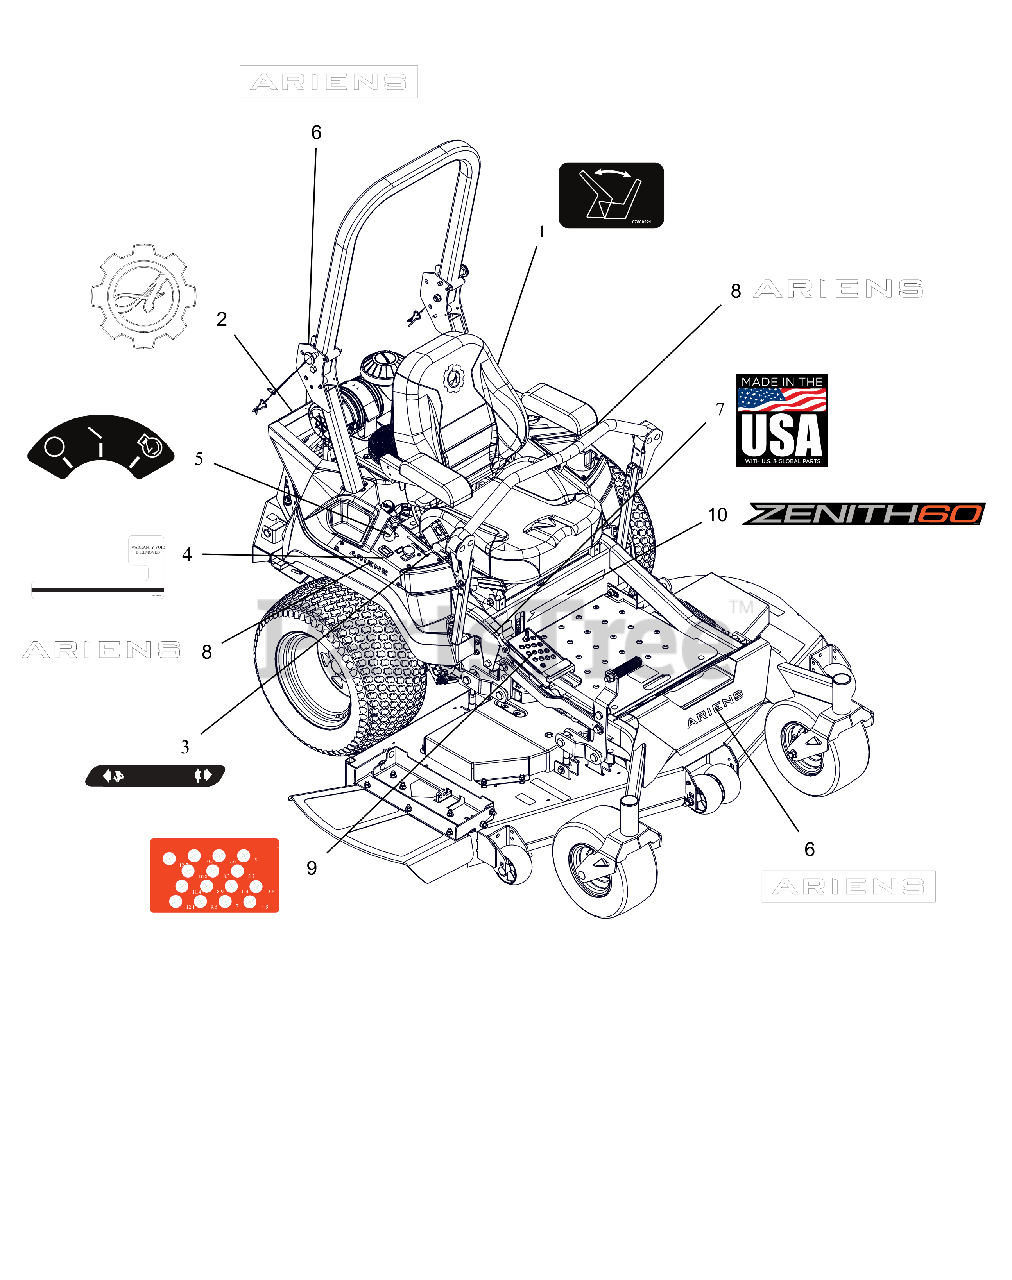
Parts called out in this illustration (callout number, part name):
1	DECAL - SEAT RELEASE
2	DECAL, ARIENS-GEAR BADGE -THK
3	DECAL, DASH DECAL
4	DECAL, ZENITH 60
5	DECAL, KEYSWITCH
6	DECAL - ARIENS 9.625"
7	DECAL, MADE IN USA
8	DECAL, ARIENS (6.50")
9	DECAL, APEX HOC METRIC
